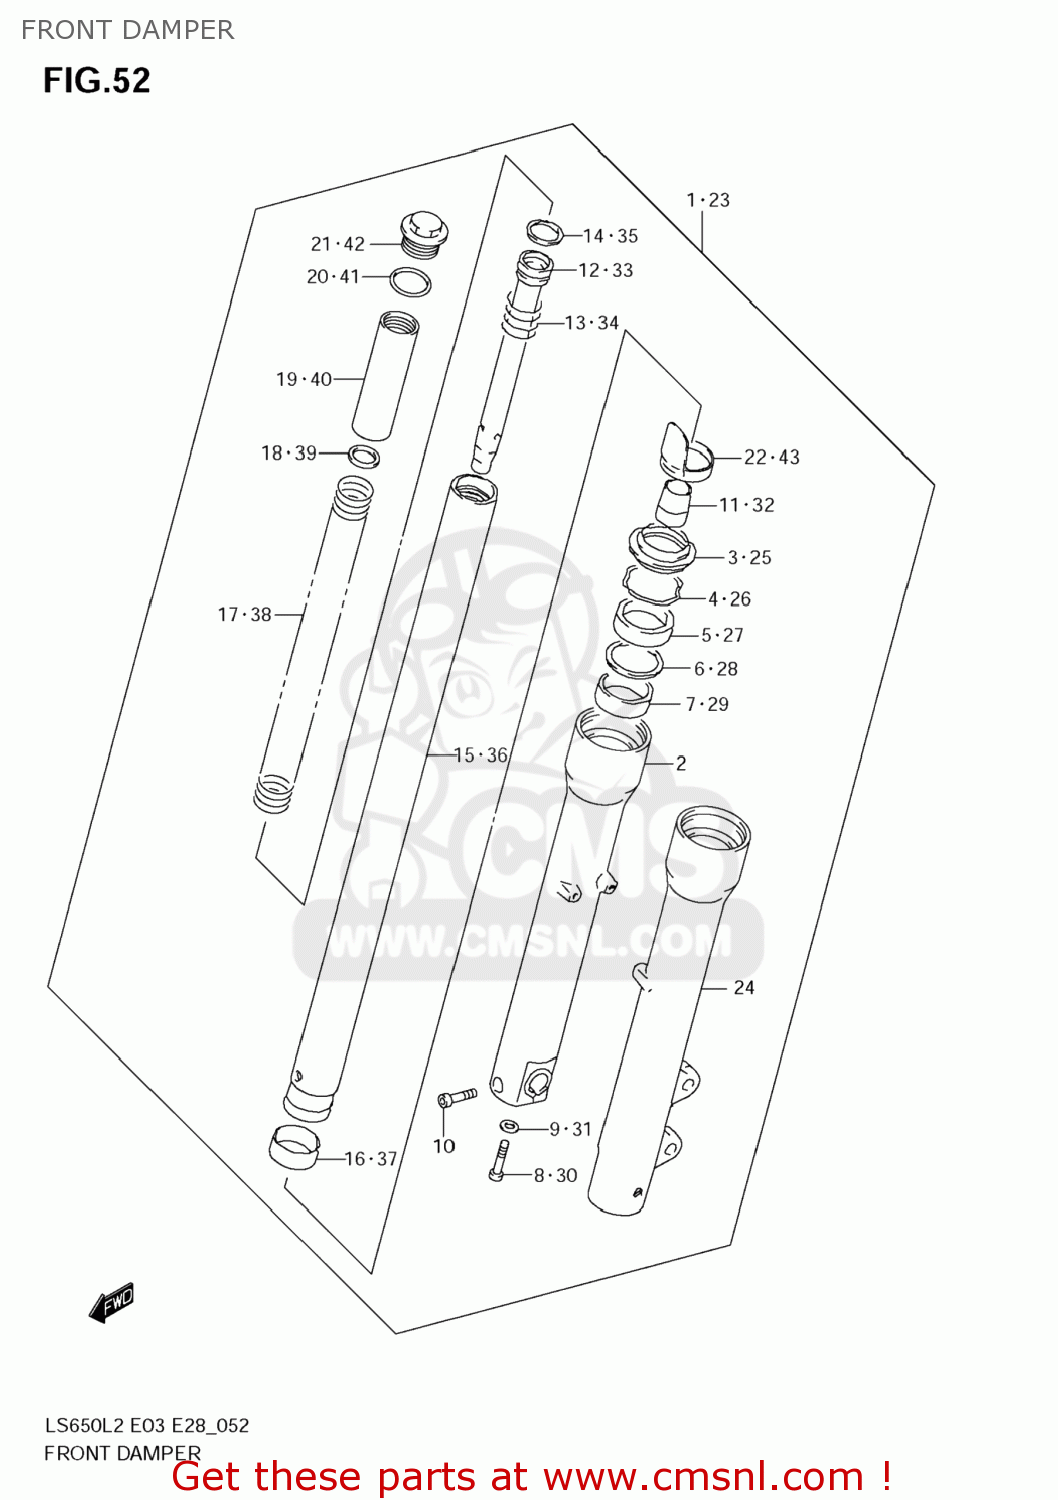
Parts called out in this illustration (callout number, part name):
1	DAMPER ASSY,FR FORK,R
2	TUBE,OUTER,R
3	SEAL,DUST
4	RING,STOPPER
5	SEAL,OIL
6	WASHER(40X50X2.3)
7	METAL,SLIDE
8	BOLT,FORK CYLINDER(10X25)
9	GASKET (NAS)
10	BOLT
11	PIECE,OIL LOCK
12	CYLINDER
13	SPRING,REBOUND
14	RING,PISTON
15	TUBE,INNER
16	PISTON
17	SPRING
18	WASHER
19	SPACER,SPRING
20	O RING
21	CAP
22	PROTECTOR,FR FORK
23	DAMPER ASSY,FR FORK,L
24	TUBE,OUTER,L
25	SEAL,DUST
26	RING,STOPPER
27	SEAL,OIL
28	WASHER(40X50X2.3)
29	METAL,SLIDE
30	BOLT,FORK CYLINDER(10X25)
31	GASKET (NAS)
32	PIECE,OIL LOCK
33	CYLINDER
34	SPRING,REBOUND
35	RING,PISTON
36	TUBE,INNER
37	PISTON
38	SPRING
39	WASHER
40	SPACER,SPRING
41	O RING
42	CAP
43	PROTECTOR,FR FORK
